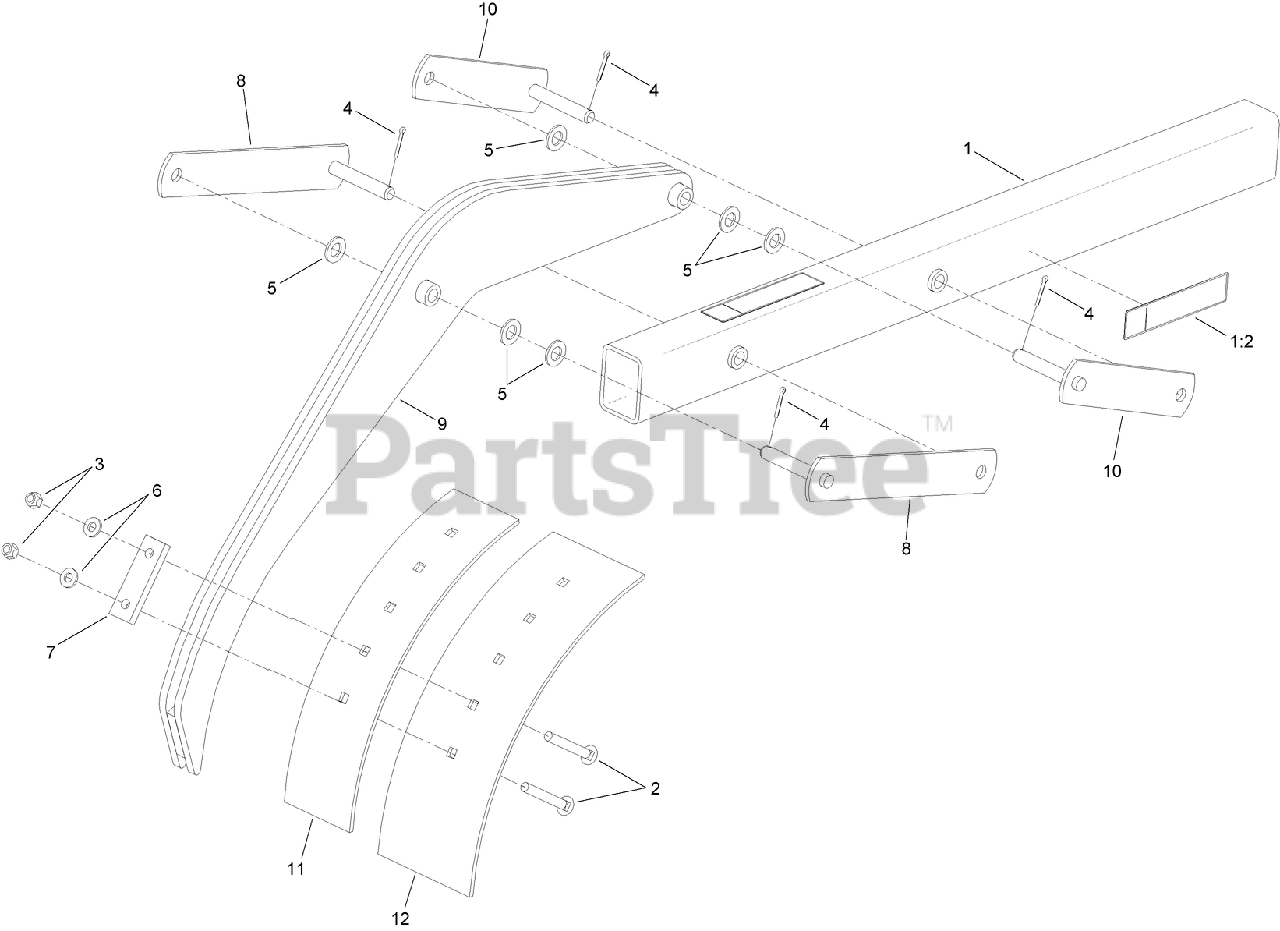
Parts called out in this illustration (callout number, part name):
1	CRUMBER TUBE ASM
1:2	DECAL-DANGER, ENTANGLEMENT
2	BOLT-CARR
3	NUT-HEX
4	PIN-COTTER
5	WASHER-FLAT
8	LINK-LONG, CRUMBER
9	ARM-CRUMBER
10	LINK-CRUMBER, SHORT
11	BLADE-MANUAL CRUMBER, 6 INCH CUT
12	BLADE-MANUAL CRUMBER, 8 INCH CUT
